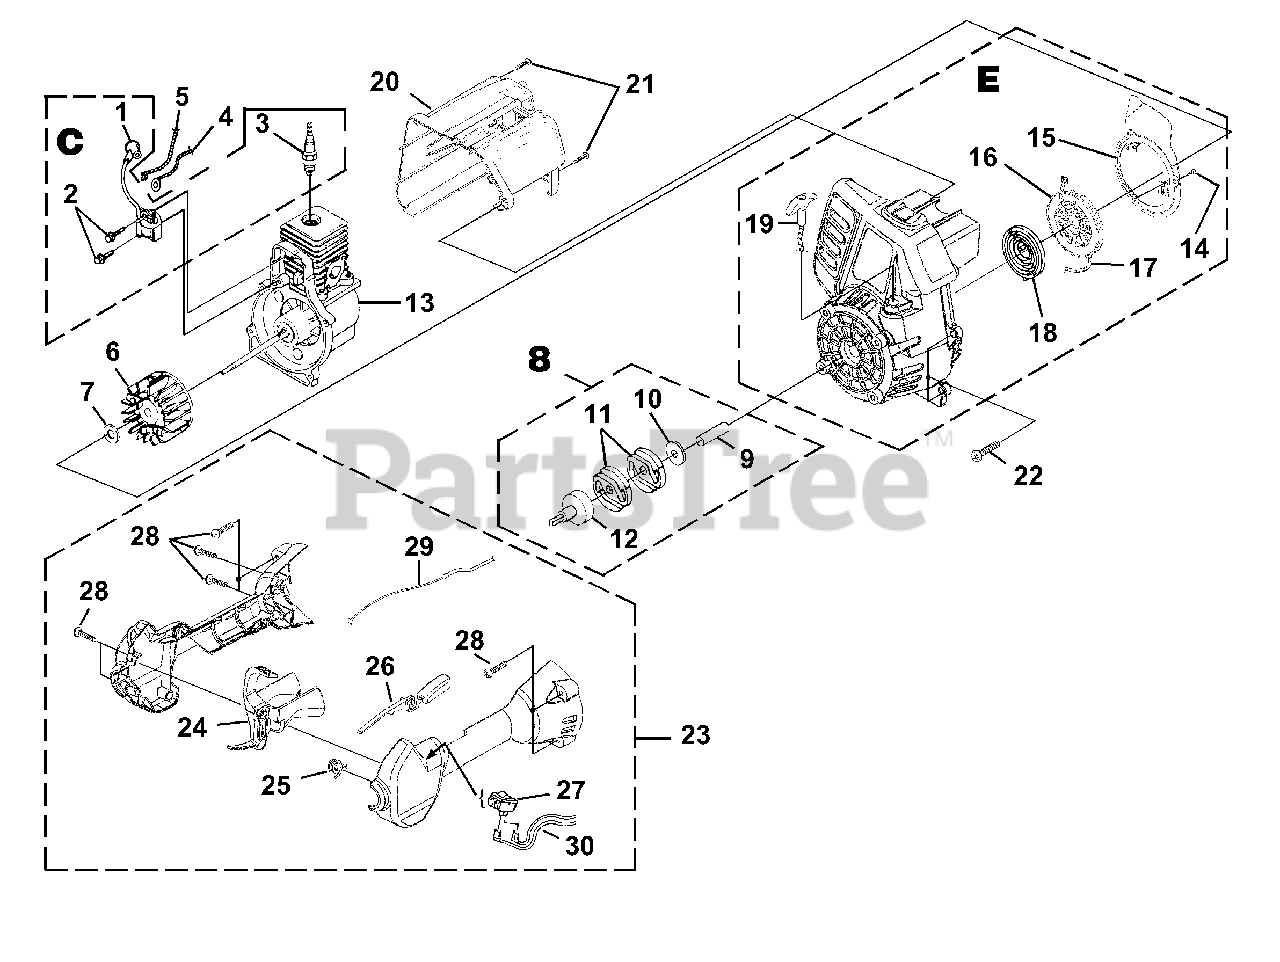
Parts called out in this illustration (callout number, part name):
1	TERMINAL & COVER
2	SCREW-Taptite (8-32 X 1")
3	SPARK PLUG
4	LEAD-Electrical
5	LEAD-Electrical
6	ROTOR KIT
7	WASHER-Flat
8	CLUTCH AND DRUM KIT
9	SPACER
10	WASHER-Flat
11	CLUTCH
12	CONNECTOR AND DRUM
13	SHORT BLOCK (See Engine Internal)
14	SCREW-Thread Form (8-16 X 1/2")
15	BAFFLE-Air
16	PULLEY-Starter
17	ROPE-Starter (42")
18	SPRING & CONTAINER
19	GRIP-Starter (Yellow)
20	HOUSING-Rear Kit
21	SCREW-Plastite (10-14 X 3/4")
22	SCREW-Taptite (10-24 X 3/4")
23	CONTROL HANDLE ASSY.
24	TRIGGER-Throttle
25	SPRING
26	THROTTLE INTERLOCK
27	SWITCH
28	SCREW-Taptite (10-14 X 1")
29	CABLE-Throttle
30	LEAD-Electrical
C	IGNITION KIT
E	COMPLETE STARTER ASSEMBLY
